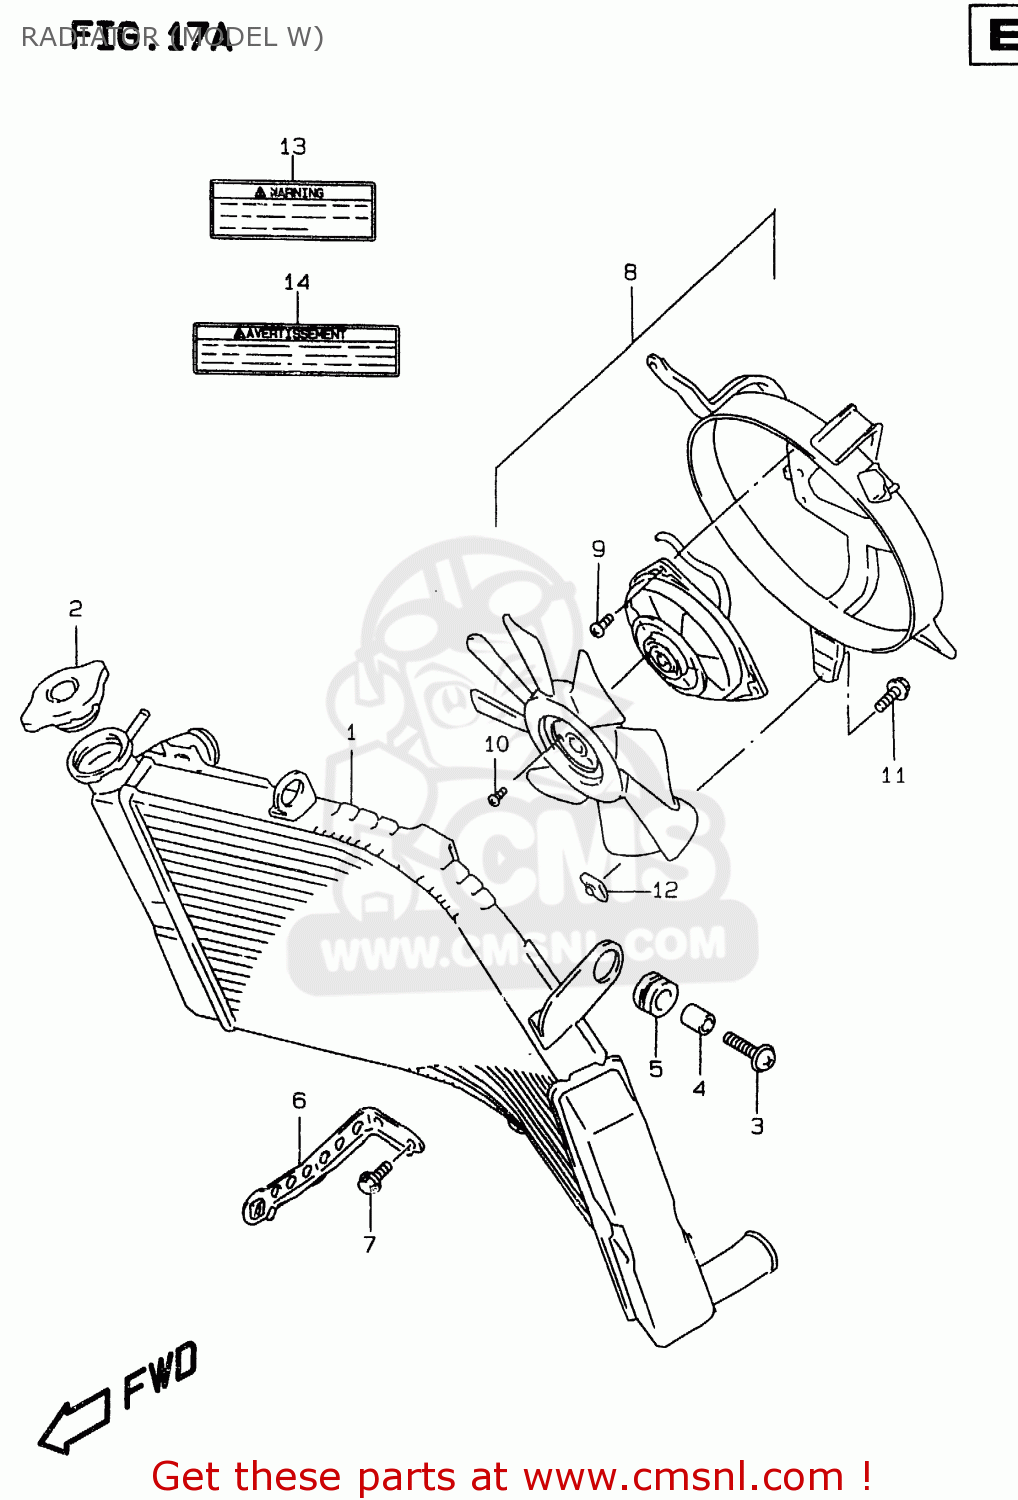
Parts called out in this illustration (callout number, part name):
1	RADIATOR ASSY,WATER
2	CAP,RADIATOR
3	BOLT 6X20
4	SPACER(6.5X10X12)
5	CUSHION
6	BRACKET,RADIATOR LWR
7	BOLT
8	FAN ASSEMBLY,RADIATOR
9	SCREW
10	SCREW 4X6
11	BOLT
12	NUT,RADIATOR COVER
13	LABEL (COOLING FAN)
14	LABEL,COOLING FAN
